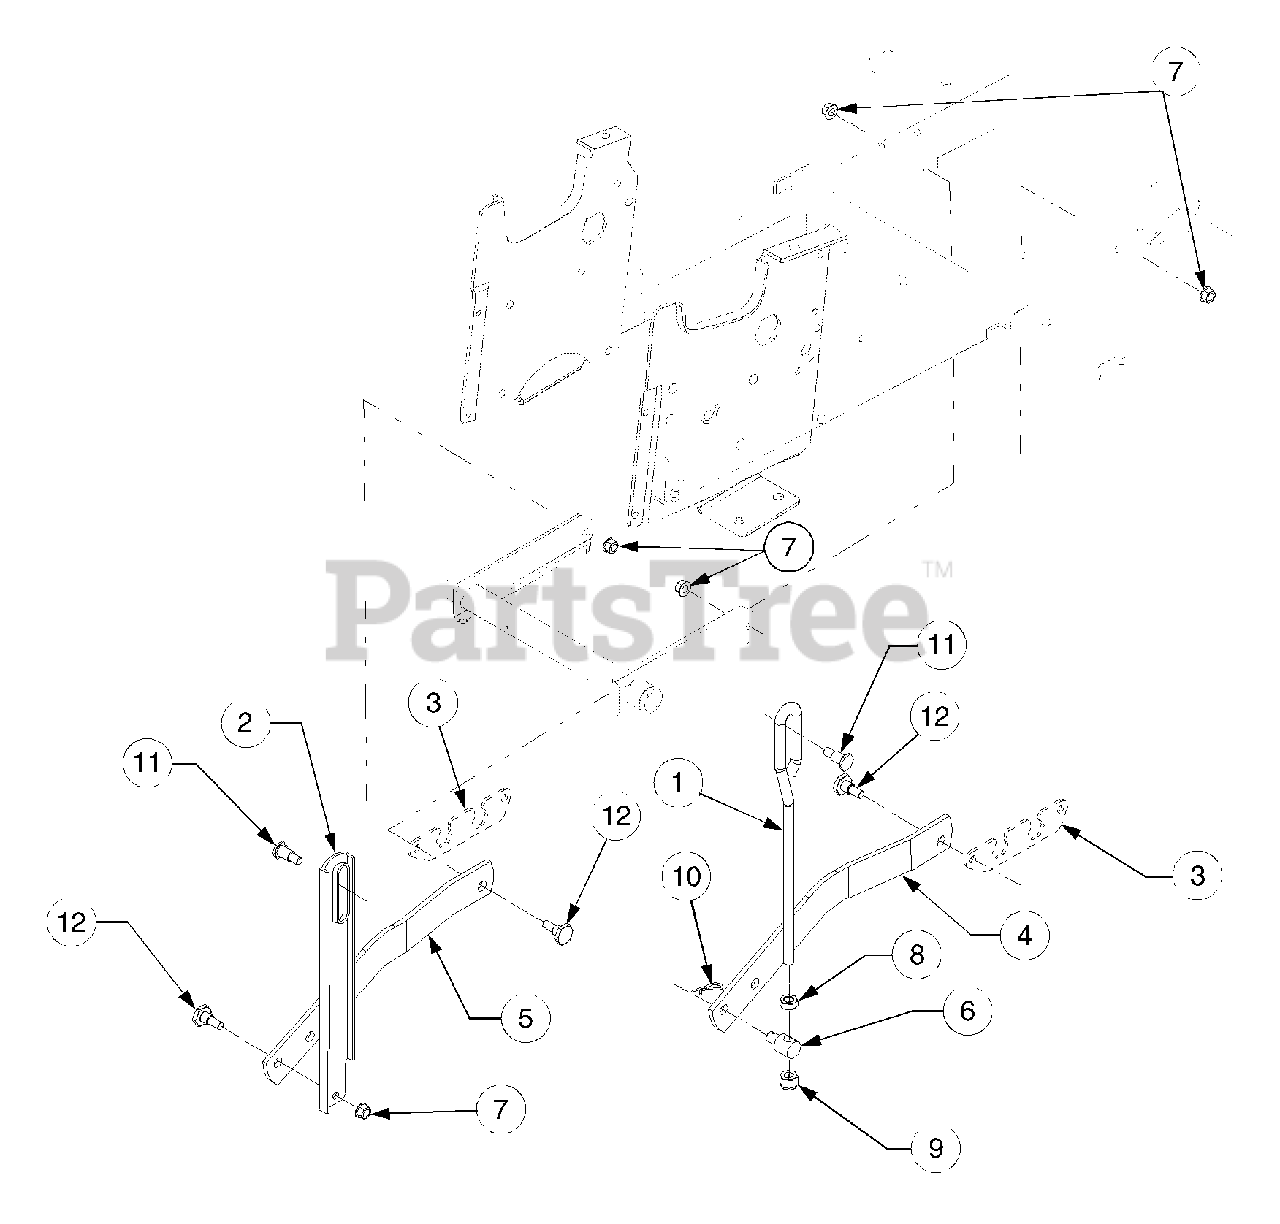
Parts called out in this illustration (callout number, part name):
1	Rod, Lift Link
7	Nut, Hex Flange Lock, 3/8-16
8	Nut, Hex Jam, 1/2-13 GR5
9	Nut, Hex Insert Lock, 1/2-13
10	Pin, Internal Cotter
11	Bolt, Shoulder
12	Bolt, Shoulder
